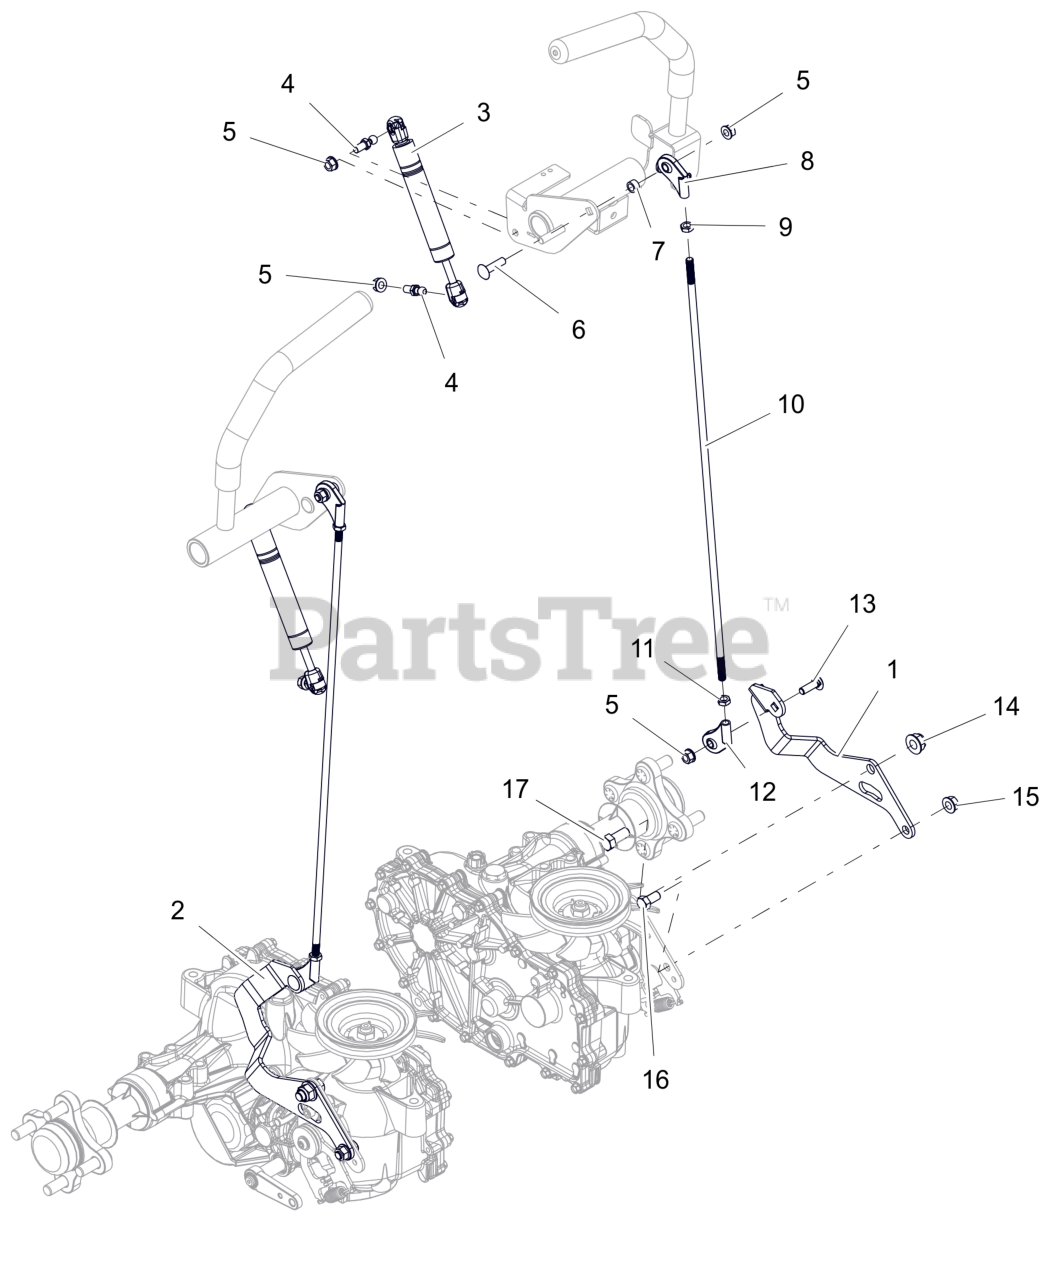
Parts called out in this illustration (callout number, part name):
1	ARM- LH DRIVE CONTROL (BLACK)
2	ARM- RH DRIVE CONTROL (BLACK)
3	DAMPER, CONTROL
4	STUD- BALL
5	NUT,LK-CTR-FLG .31-18 GF ZCC
6	BTL,RHSSN .313-18 X 1.25 G5 ZCC
7	SPCR- SLV .344 X .500 X .283
8	END, ROD 5/16-24 RH
9	NUT-JAM .312-24 ZCC
10	LINKAGE- DRIVE CONTROL
11	NUT, JAM-LH .312-24 ZCC
12	END, ROD 5/16-24 LH
13	BLT,RHSSN .31-18X1.00 G5 ZCC
14	NUT,NYL-FLG .44-14 GF ZCC
15	NUT-LK-CTR-FLG .375-16 GF ZCC
16	BLT,HEX .38-16X.75 G5 ZCC
17	BLT, HEX 0.4375-14X1 GR5 ZCC
